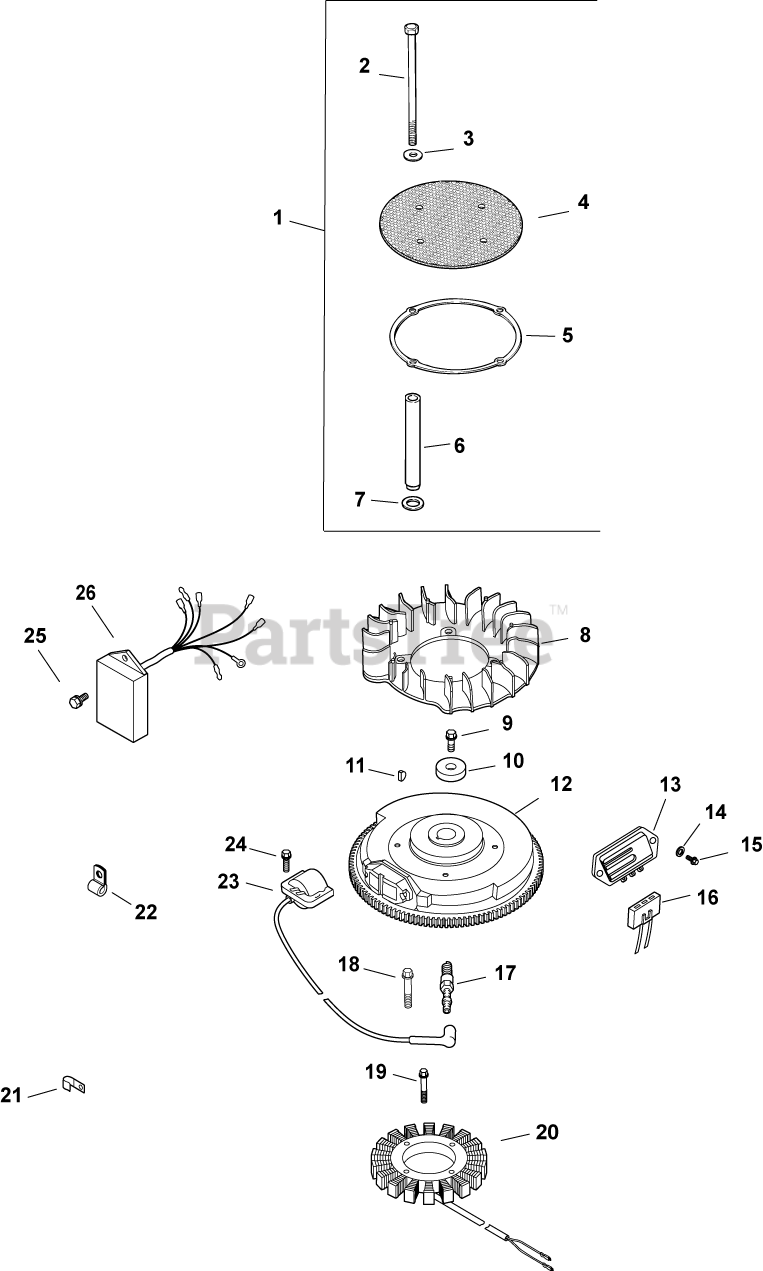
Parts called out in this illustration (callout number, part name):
1	KIT, CHOPPER SCREEN
2	SCREW, SOCKET TRUSS HD CAP
3	WASHER, FLAT 1/4" (O.D. 5/8")
4	SCREEN, GRASS-USE 24 162 41-S
5	RING, SUPPORT USE 25 141 08-S
7	WASHER, SPRING 10 MM
8	FAN (WITH HOLE)-USE 24 157 16-S
9	SCREW, FLG M10X1.5X45 - (#25086361S)
10	WASHER, FLAT 13/32"
11	KEY, 3/16" X 5/8"
12	FLYWHEEL ASSEMBLY - USE 24 025 14-S
14	WASHER, FLAT 3/16"
15	SCREW, PHL HD #11-16X7/8"
16	CONNECTOR, BODY (KM)-USE 25 155 41-S
18	SCREW, M5X0.8X25 - (#25086402S)
19	SCREW, SKT SET #10-24X1/4"
20	KIT, 15 / 20 AMP STATOR
22	CLIP, CABLE
24	SCREW, SKT THD FRM M5X0.8X25
25	SCREW, PHL HD #11-16X1/2"
26	MODULE, SPEED ADVANCE
